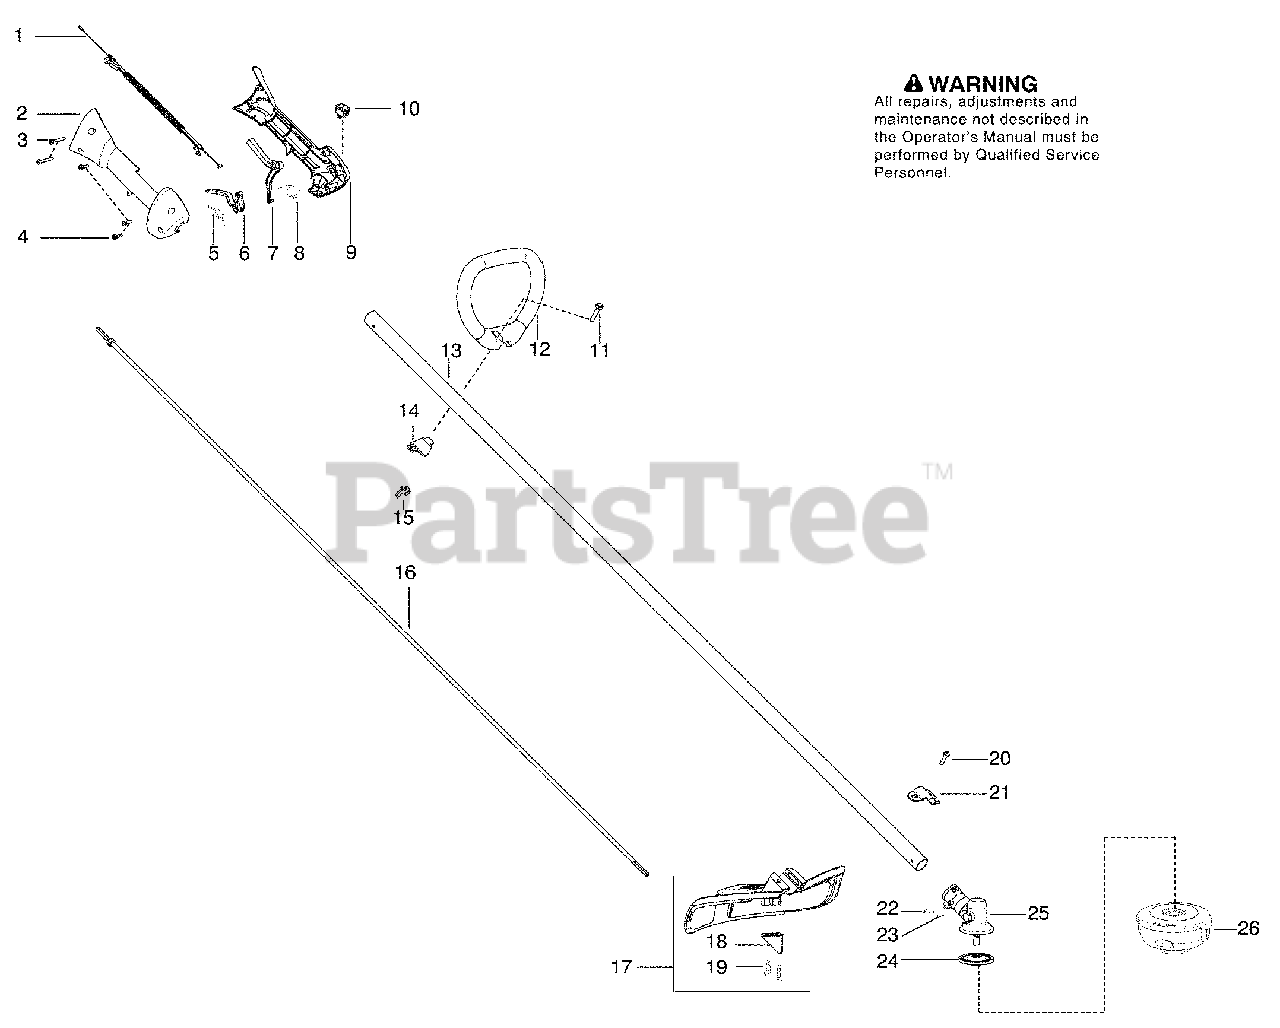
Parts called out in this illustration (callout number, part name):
1	Assy-Cable/Wire Harness
2	Housing-Throttle (RH)
5	Spring-Trigger
7	Lockout-Throttle
8	Spring-Lockout
9	Housing-Throttle (LH)
10	Kit-Switch
12	Handle-Assist
13	Kit-Driveshaft SST
14	Clamp-Handle
15	Wingnut
16	Flex shaft
17	Kit-Shield
18	Limiter-Line
21	Bracket-Shield
24	Driver Disc
25	Assy-Gearbox
26	Assy-T25 Cutting Head
